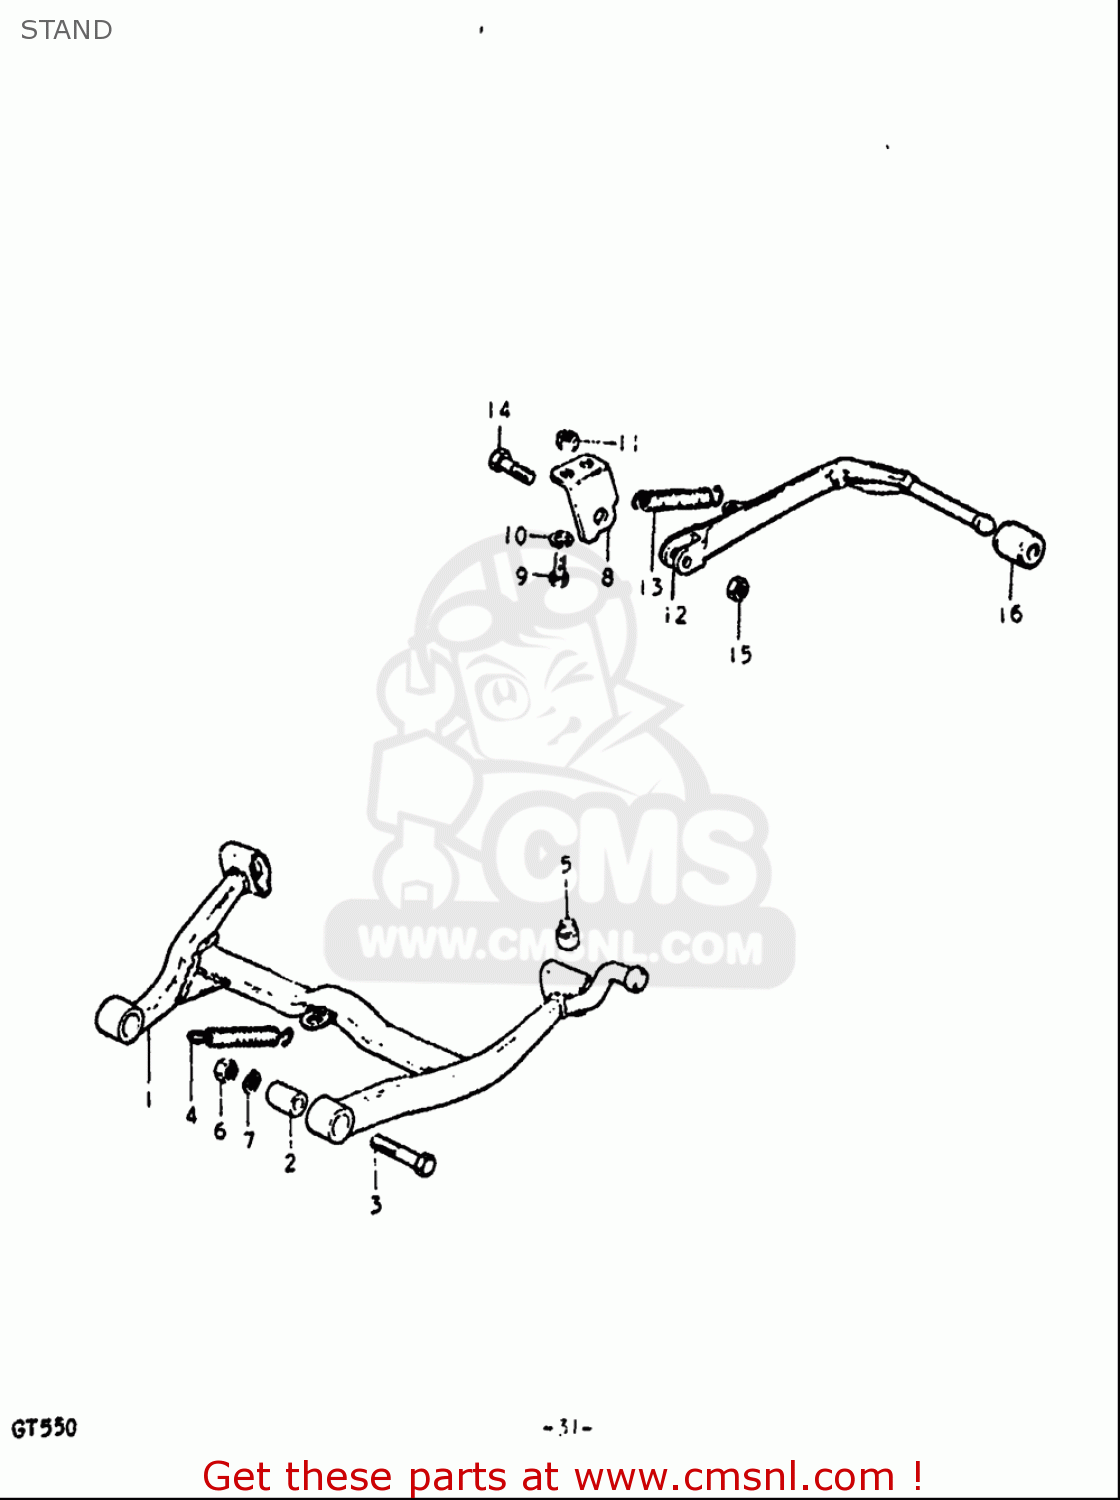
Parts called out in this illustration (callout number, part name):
2	SPACER(10.5X16X30)
3	BOLT(10X48)
4	SPRING
5	CUSHION
6	NUT
7	WASHER,LOCK
9	BOLT(10X27)
10	WASHER,LOCK
11	NUT
13	SPRING
14	BOLT(10X27)
15	NUT
16	CUSHION
